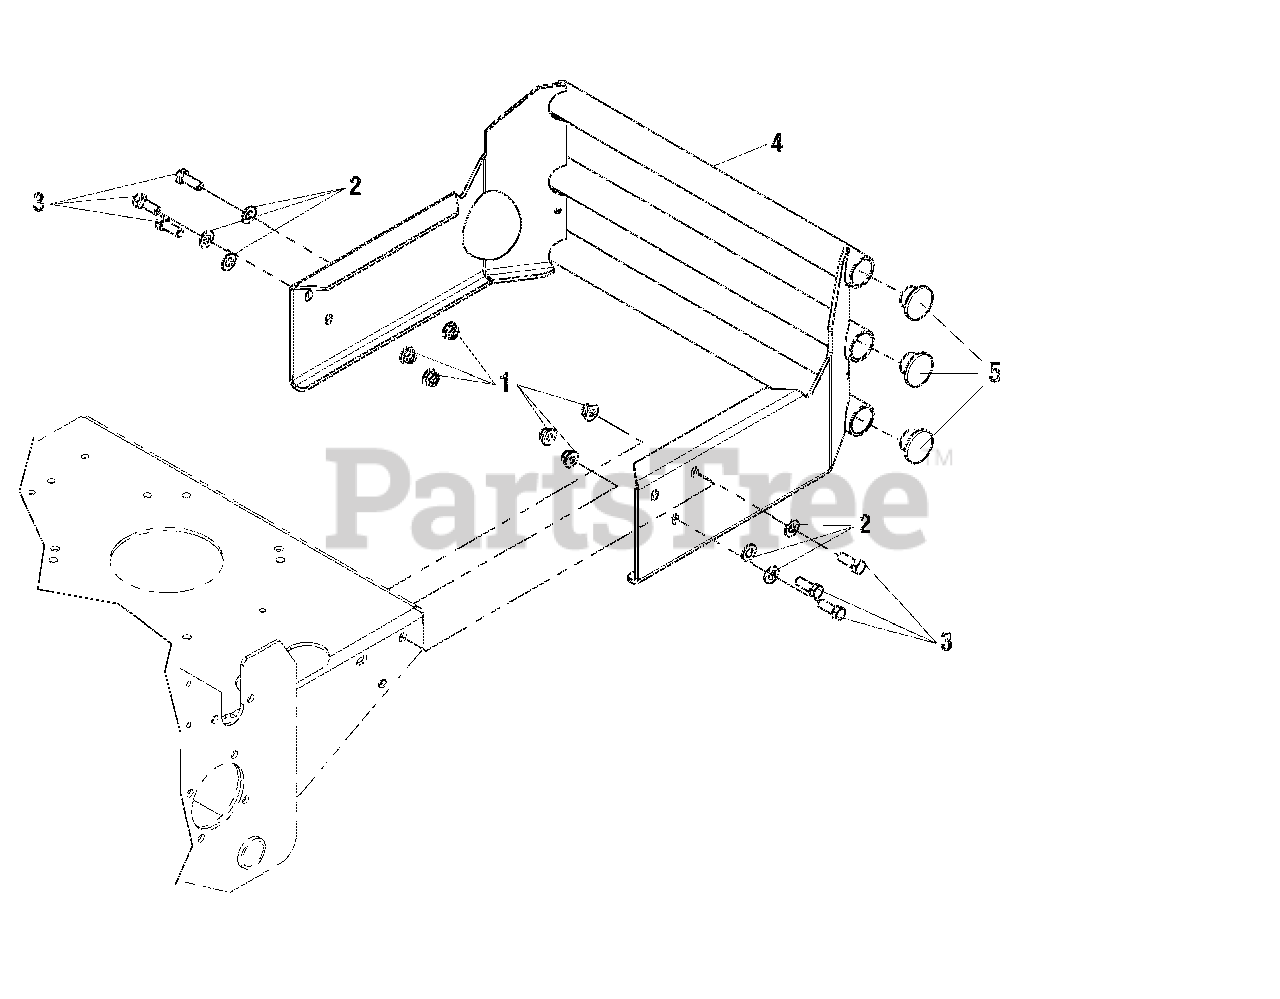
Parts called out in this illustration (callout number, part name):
1	NUT, 3/8-16 HEX NYLOCK FLANGE
2	WASHER, 3/8 GD.9 FLAT
3	BOLT, 3/8-16 X 1" GD5 CZ
4	WELD, BUMPER, V-TWINS - RED
5	PLUG, PANEL, 1.25 - BLACK
